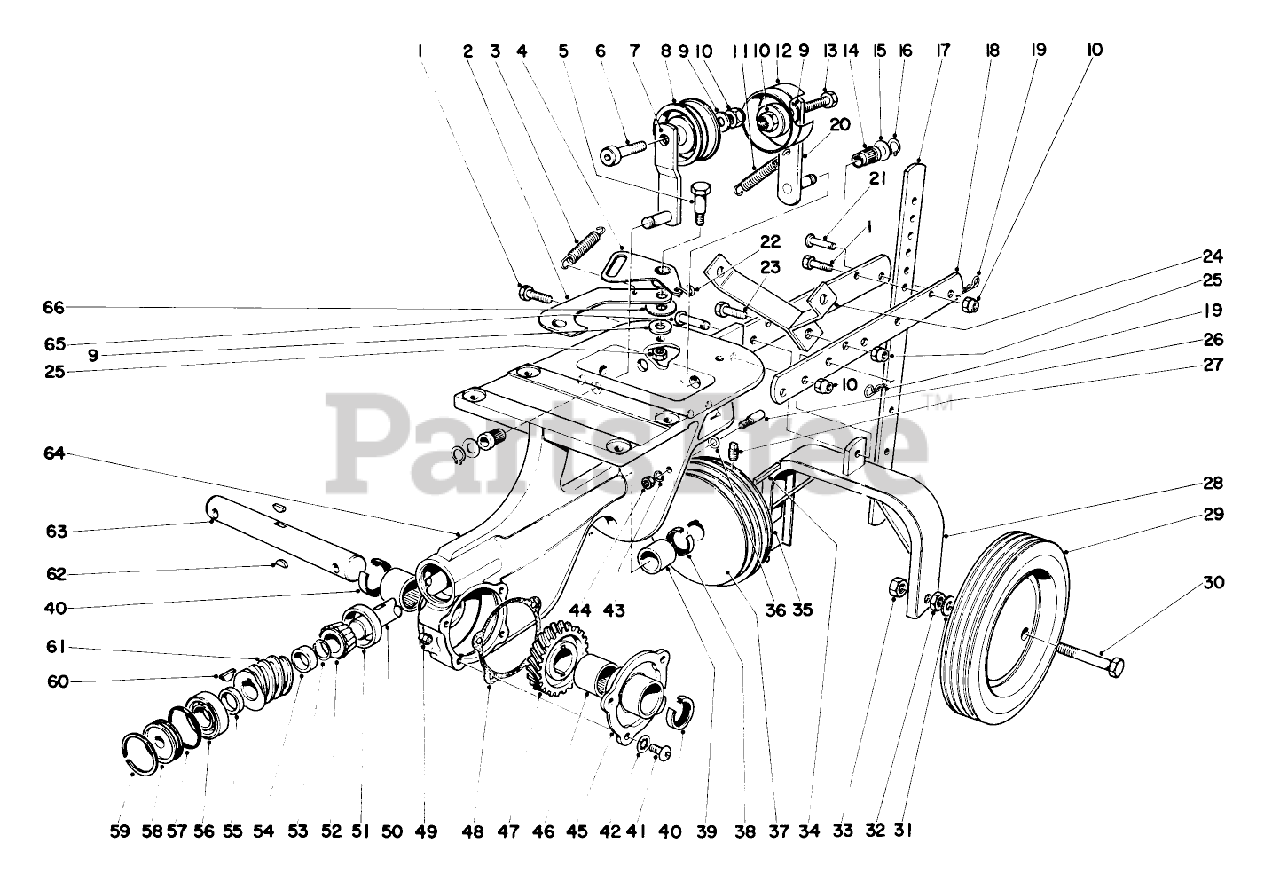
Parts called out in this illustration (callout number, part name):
1	SCREW-HH
2	Rev. Link
3	Spring
4	Bellcrank
5	SCREW-SHOULDER, HH
6	Capscrew
7	IdlerArm
8	PULLEY IDLER
9	WASHER-FLAT
10	NUT-LOCK, CONE
11	Spring
12	IDLER PULLEY
13	SCREW-HH
14	IDLER BRG
15	WASHER-PLAIN
16	RING-RETAINING, EXT
17	DEPTH GAGE
18	Drawbar
19	PIN-COTTER, HAIR
20	Idler
21	Pin
22	S Hook
23	SCREW-HH
24	Handle Support
25	NUT-LOCK, CONE
26	Belt Guide
27	SCREW-SET, HSH
28	Wheel Bracket
29	Wheel
30	Axle
31	WASHER-FLAT
32	NUT-JAM
33	1/2-13 CONELOCK NUT
34	KEY-SQUARE
35	Pulley
36	WASHER-FLAT
37	Pulley
38	SEAL-OIL
39	BUSHING
40	SEAL-OIL
41	SCREW-HSBH
42	WASHER-LOCK
43	WASHER-LOCK/EXT
44	NUT-JAM
45	Cover
46	Bearing
47	WORM WHEEL
48	GASKET
49	PLUG-PIPE, SQH
50	WORM SHAFT
51	1.750 ROLLER BRG CUP
52	3/4 ROLLER BRG CONE
53	RETAINER RING
54	WORM SHF REAR SPACER
55	SPACER
56	.750 BALL BEARING
57	O-RING
59	INTRNL RETAINING RING
60	KEY-WOODRUFF
61	WORM GEAR
62	KEY-WOODRUFF
63	WORM WHEEL SHAFT
64	Chassis
65	Pin
66	WASHER-FLAT
